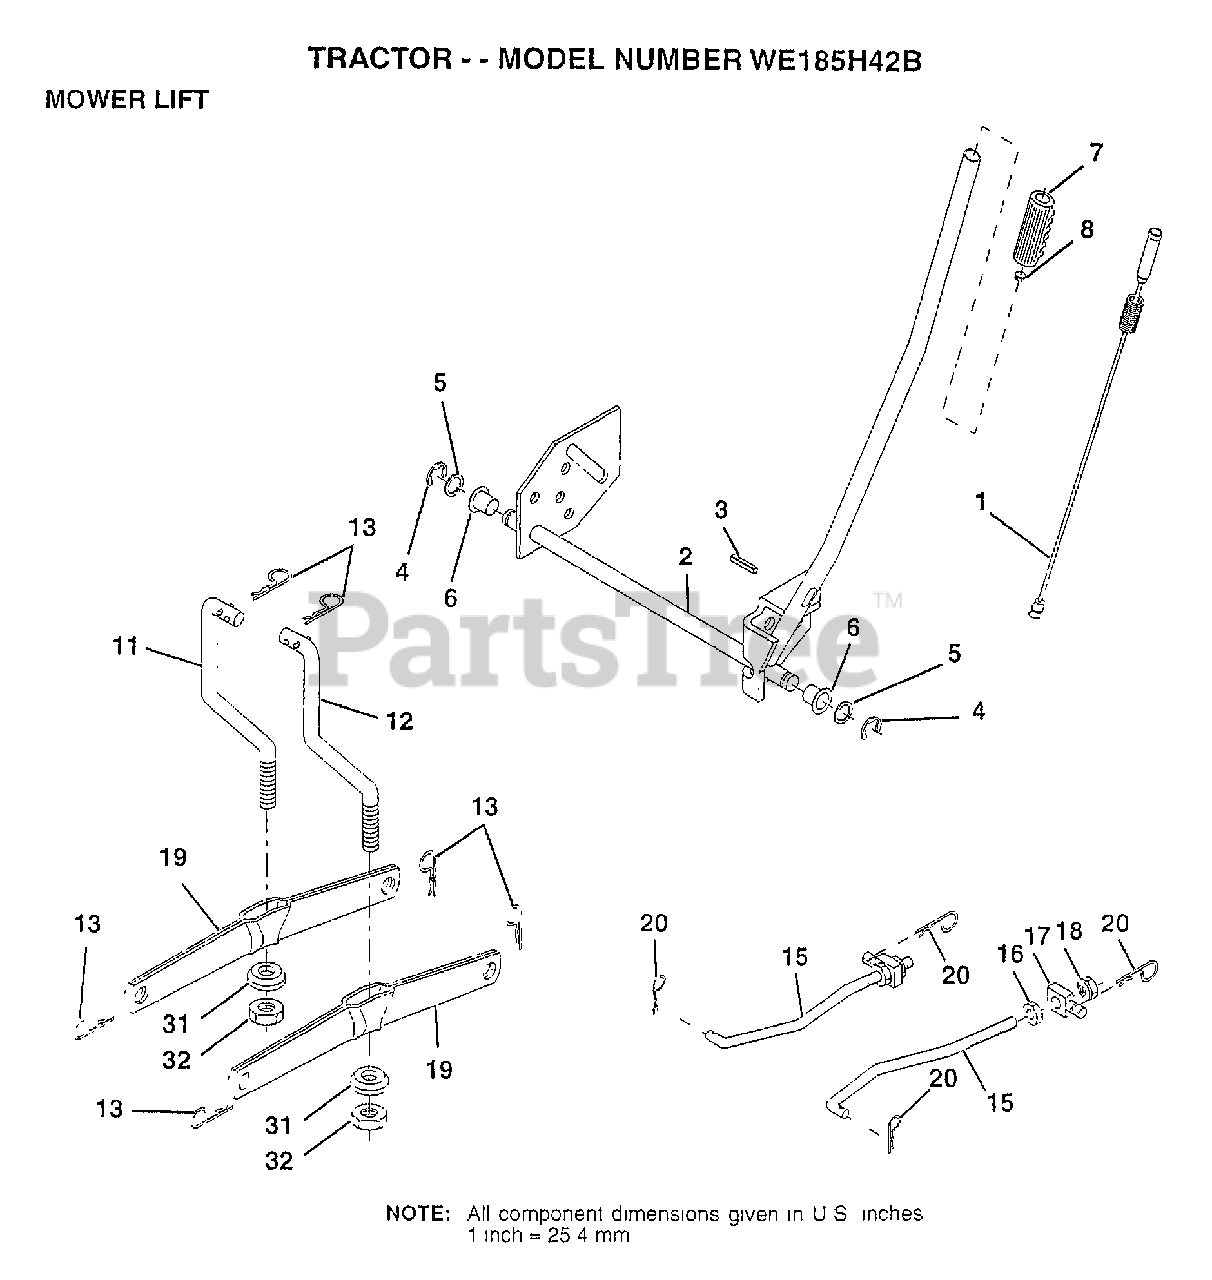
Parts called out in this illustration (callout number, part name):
1	WIRE ASM W.SPRING
2	"SHAFT ASM LIFT,RH"
3	PIN-GROOVE LT
5	WASHER
6	NYLON BEARING
7	GRIP
15	LINK.FRONT
16	NUT
17	TRUNION
18	NUT.LK.W/WSH.1/2.
19	ARM SUSP REAR
20	RETAINER.SPRING
31	BEARING PVT LH
32	NUT.CROWNLOCK.3/8
